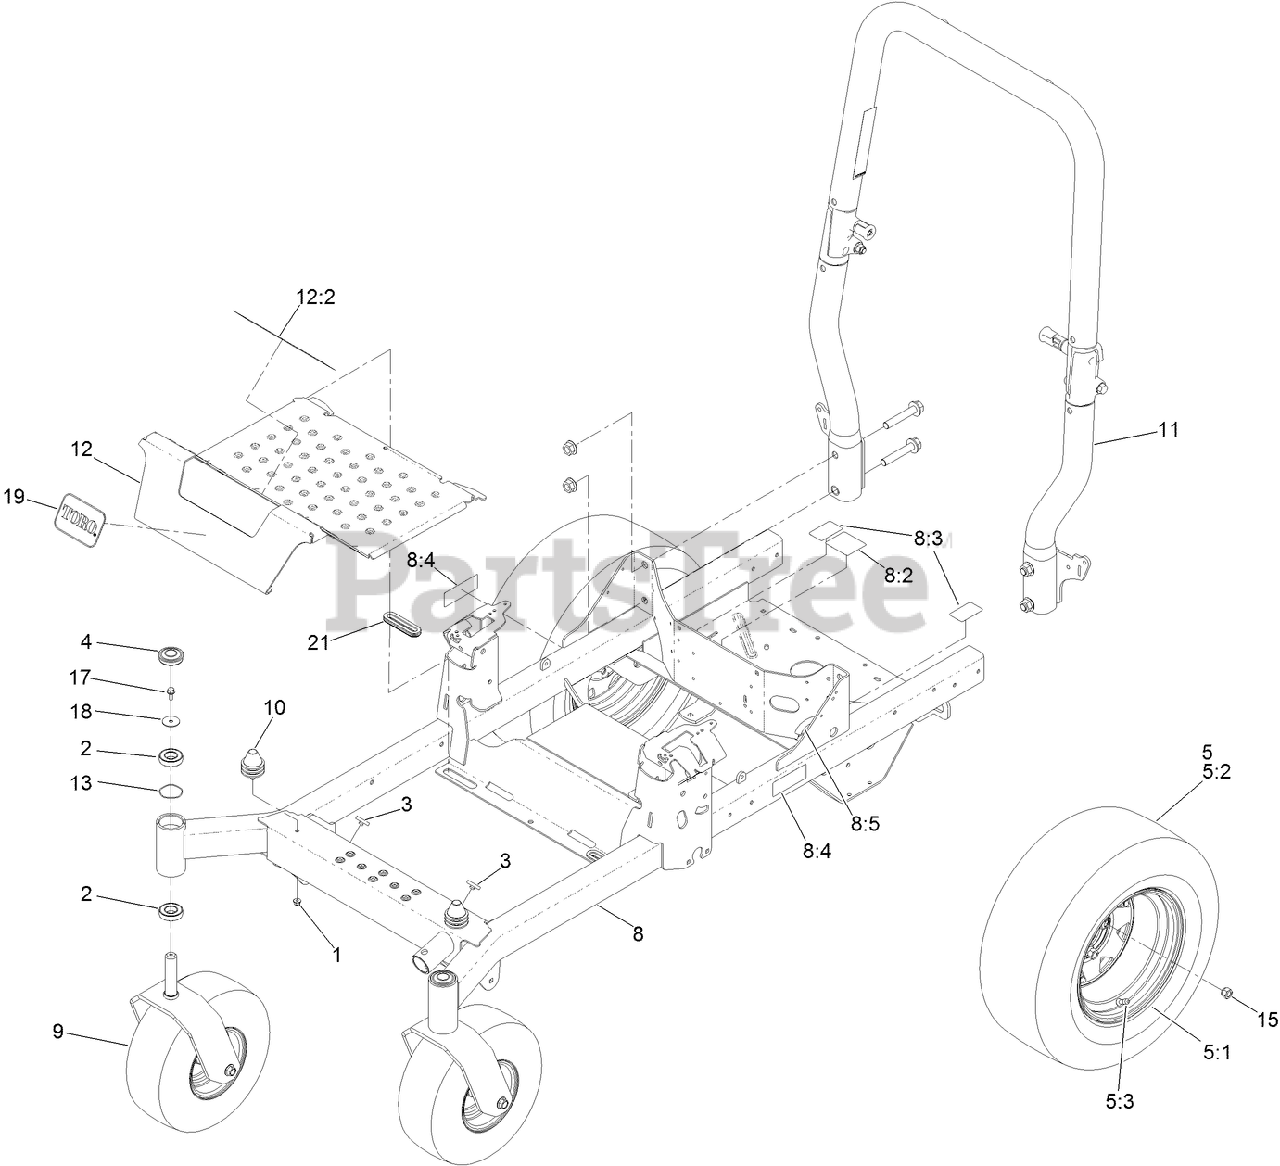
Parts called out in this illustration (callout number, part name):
1	NUT-HF, NI
2	BEARING-BALL
3	BUMPER-PUSH-IN, RUBBER
4	CAP-GREASE
5	WHEEL AND TIRE ASM
5:1	RIM-WHEEL
5:2	TIRE
5:3	STEM-VALVE
8	FRAME ASM
8:2	DECAL-ROUTING, BELT
8:3	DECAL-RELEASE, DRIVE
8:4	DECAL-WARNING
8:5	STRIP-SEAL
9	FRONT CASTER ASM (W/FORK)
10	ISOLATOR
11	ROPS ASM
12	PAN-FLOOR
12:2	DECAL-DANGER
13	SPRING
15	NUT-LUG
17	SCREW-HHF
18	WASHER-FLAT
19	DECAL
21	GROMMET-RUBBER
